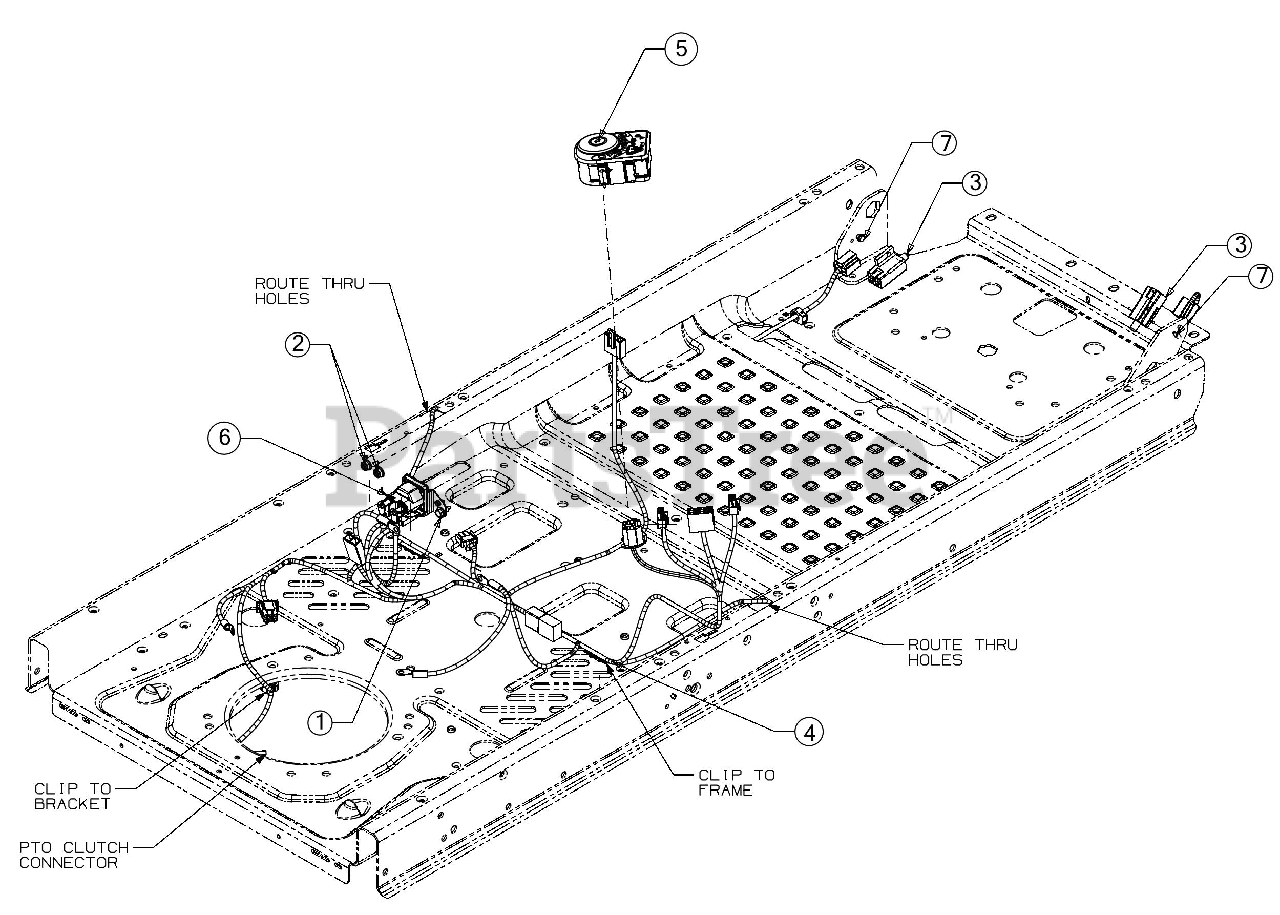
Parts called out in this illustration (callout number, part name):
1	SCREW 1/4-20X.625
2	FLANGE LOCK NUT
3	INTERLOCK SWITCH (NO/NC)
4	MAIN HARNESS
5	KEY SWITCH MODULE 8 PIN
6	SOLENOID-12V 100A
7	SHOULDER SCREW
